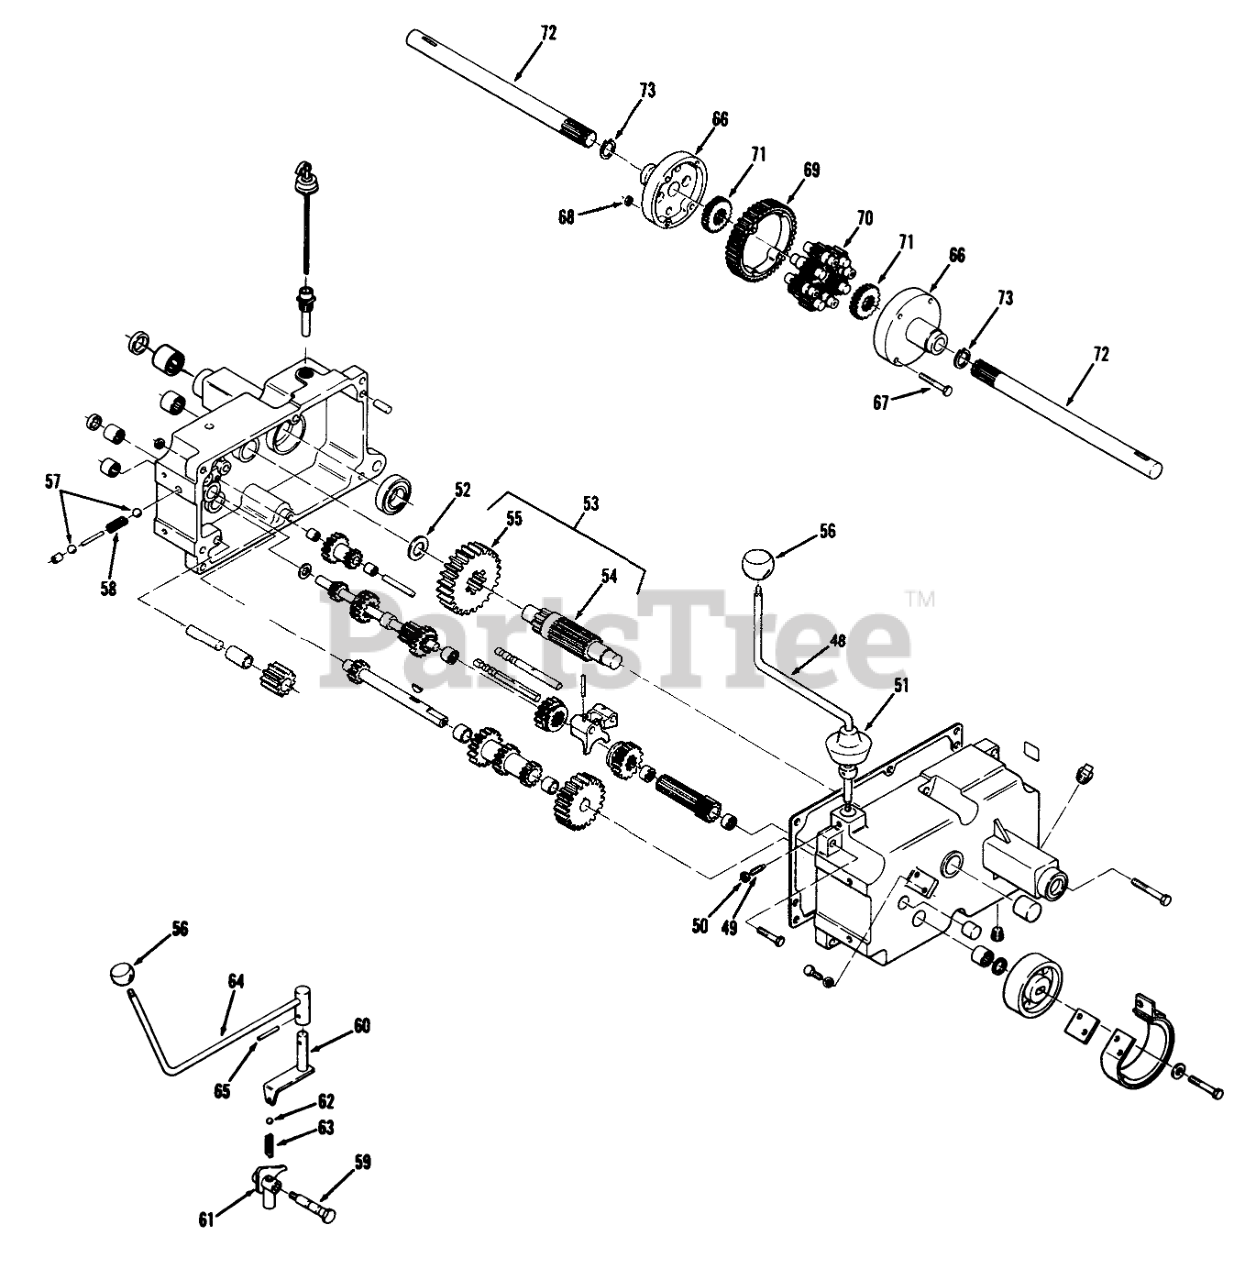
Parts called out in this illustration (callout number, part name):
48	Shift Stick & Collar
49	SETSCREW
50	Nut
51	COVER-DUST
52	WASHER-THRUST
53	GEAR ASM
54	PINION SHAFT
56	SHIFT KNOB
57	BALL-DETENT
58	Spring
59	BOLT-DETENT
60	SHIFT ASM
61	Shift Fork
62	BALL-DETENT
63	Spring
64	Handle-Shift
65	PIN-SPIROL
66	DIFFERENTIAL END CAP
67	BOLT-HEX
68	NUT
69	GEAR-DIFFERENTIAL RING, 43T
70	GEAR-PINION, 11T
71	GEAR-AXLE DIFFERENTIAL
72	AXLE-REAR
73	RING-SNAP
